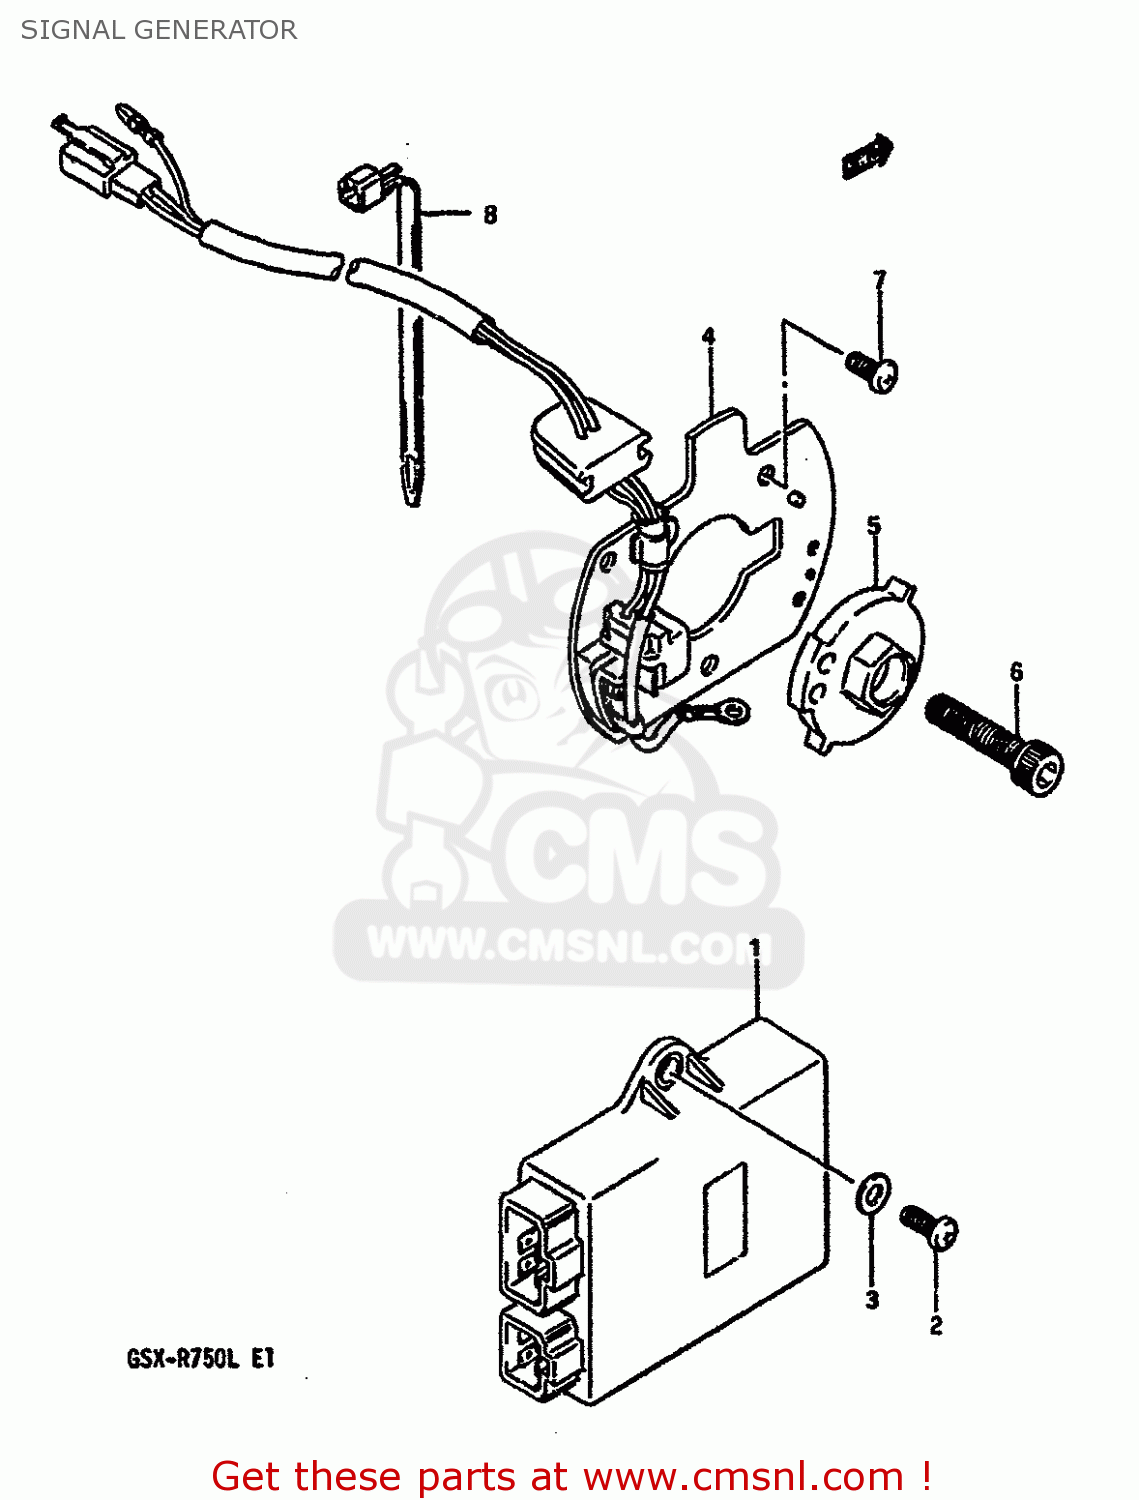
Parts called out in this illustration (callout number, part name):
1	IGNITOR
2	SCREW
3	WASHER, LOWER
4	GENERATOR ASSY,SIGNAL
5	ROTOR,SIGNAL
6	BOLT
7	SCREW
8	CLAMP(L:125)
